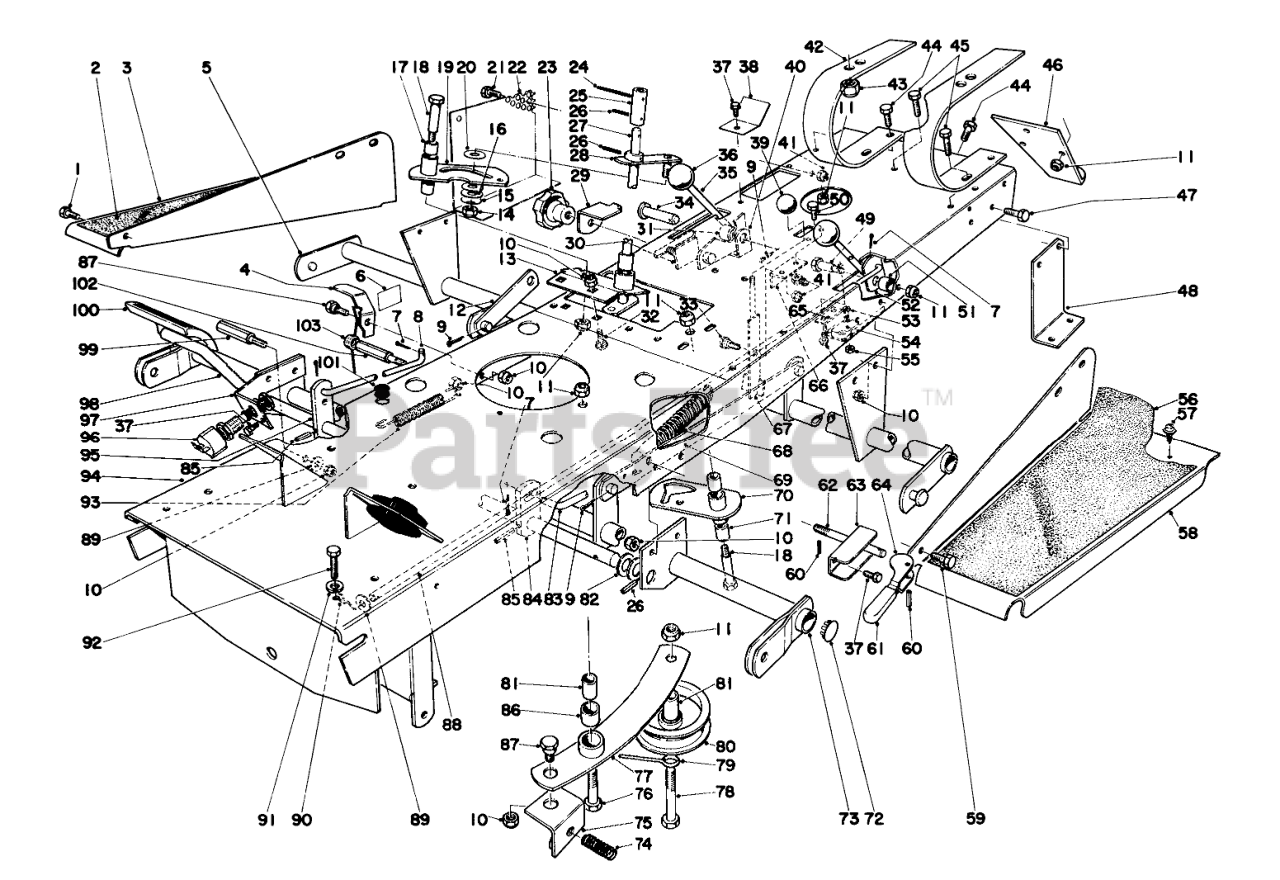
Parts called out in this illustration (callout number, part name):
1	SCREW-HH
2	Pad R. H.
3	Footrest R.H.
4	Latch
5	Cross Tube
6	Decal Brake
7	PIN-COTTER
8	Link Neutralizer
9	PIN-COTTER
10	NUT-LOCK, CONE
11	NUT-LOCK, CONE
12	Lift Link
13	Bracket-Control
14	NUT-LOCK, NI
15	WASHER-SPRING
16	WASHER-FLAT
17	BUSHING
18	Axle Bolt
19	Cam Plate (Incl. Ref. #17)
20	Washer
21	SCREW-HH
22	Fan Guide Side
24	Roll Pin
25	Sleeve Handle
26	PIN-SPRING
27	Handle Hydro Control
28	Control Crank
29	Slide
30	Knob Plate
31	Spacer
32	BOLT-CARR
33	Shoulder Bolt
35	Lever
36	Knob
37	SCREW-HH
38	Shield Fan
40	Support Height of Cut Lever
41	NUT-LOCK, CONE
42	Seat Spring
43	1/2-13 CONELOCK NUT
44	SCREW-HH
45	Capscrew
46	Hitch
47	SCREW-HH
48	Axle Support L.H.
49	Shoulder Bolt
50	SCREW-HH
51	Spacer
52	Lever
53	SCREW-HEAD, PAN
54	MICRO SWITCH
55	NUT-LOCK, NI
56	Pad Left
57	10-16 X 3/8 THDG SCREW
58	Footrest
59	SCREW-HH
60	PIN-ROLL
61	Handle Grip
62	Adjustment Rod
63	Retainer Idler
64	Idler Crank
65	Bracket Switch
66	Bracket Pivot
67	Drive Lever
68	Spring Counterbalance
69	Lift Equalizer
70	Plate Neutralizer (Incl. Ref. #71)
71	BUSHING
72	Plug Button
73	Cross Tube Front
74	Compression Spring
75	Swivel Bracket
76	SCREW-HH
77	Idler Bracket (Incl. Ref. #86)
78	SCREW-HH
79	Belt Retainer
80	Flat Idler
81	Idler Spacer
82	WASHER-FLAT
83	Brake Rod Front
84	Lever Brake
85	PIN-ROLL
86	.503ID X .875LG BSHG
87	Screw
88	Rod Clutch
89	WASHER-FLAT
90	PIN-COTTER
91	WASHER-LOCK
92	He Ha. Screw
93	Spring
94	Frame
95	Pedal Crank Neutralizer
96	Neutral Switch
97	Bracket Switch
98	Pedal
99	Pedal Stop
100	PAD-BRAKE
101	GROMMET
102	Brake Stop
103	Spring-Brake Latch
